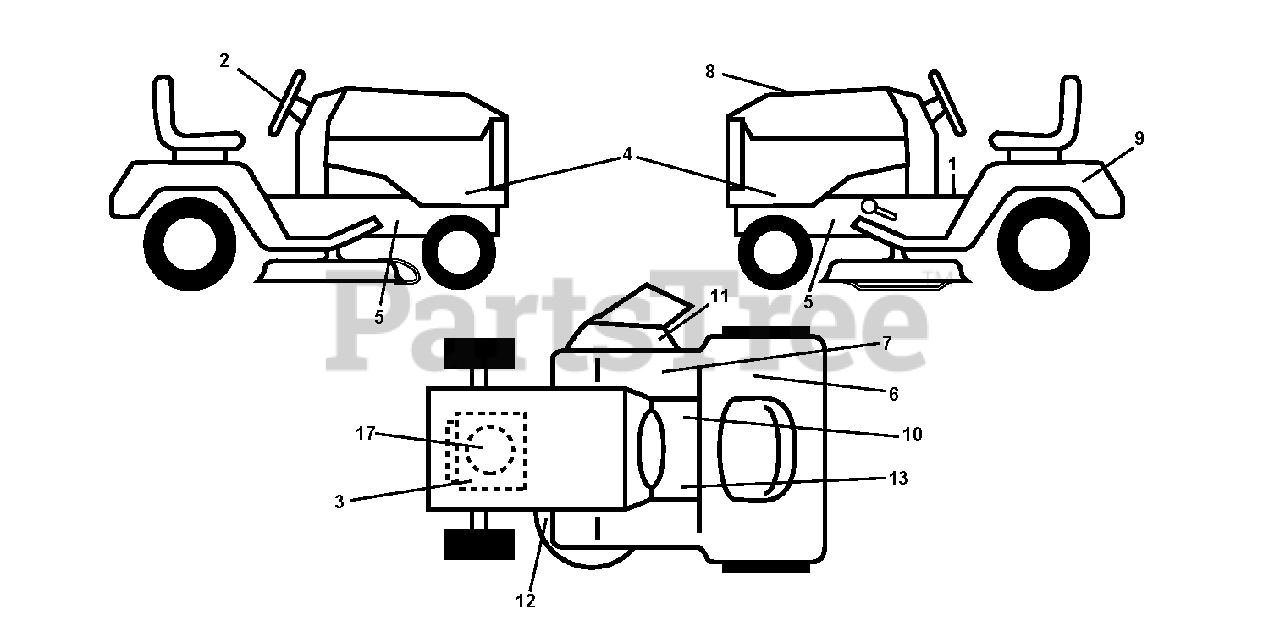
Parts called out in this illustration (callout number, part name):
9	DECAL BTRY SYMBOLS
10	DECAL PARK BRAKE
11	DECAL, WARN. DEFLECT/CTFGR
